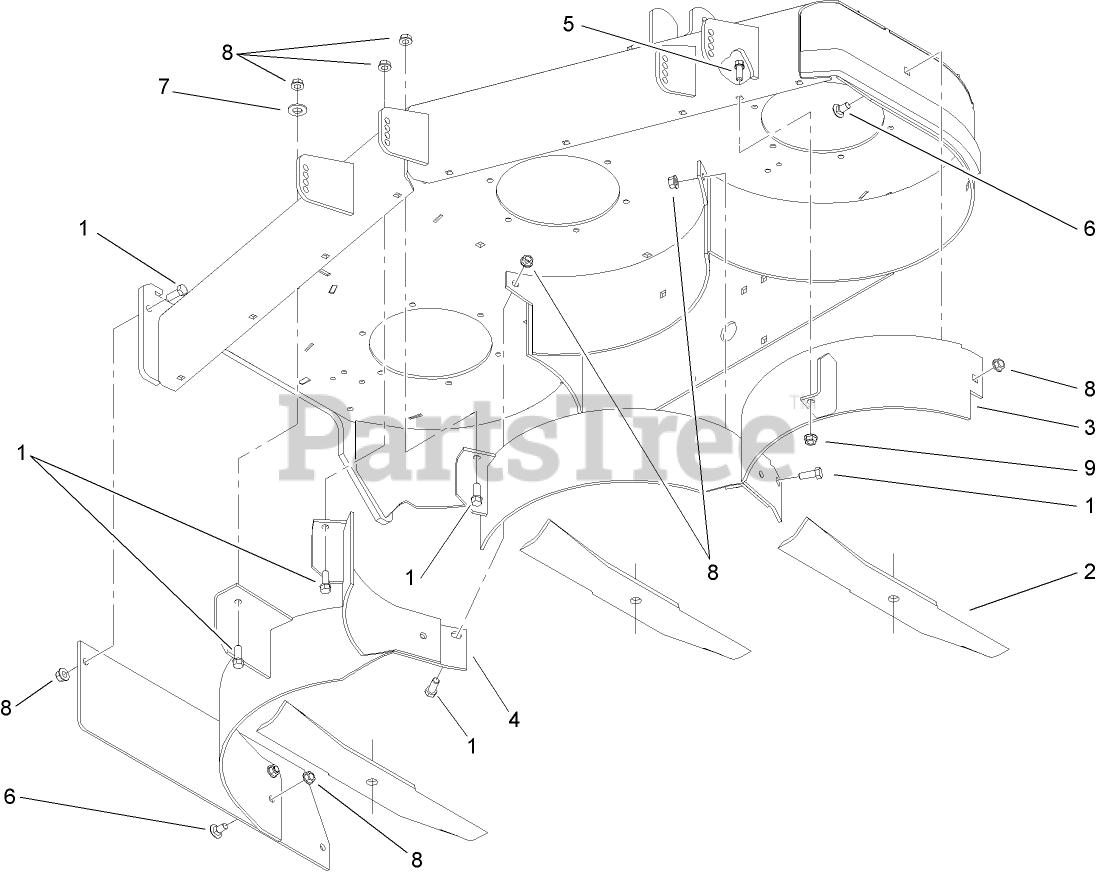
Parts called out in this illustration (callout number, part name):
1	SCREW-HWH
2	BLADE-RECYCLER, 16.5 INCH
3	LEFT BAFFLE ASM
4	RIGHT BAFFLE ASM
5	BOLT-CARR
6	SCREW-CARR
7	WASHER-FLAT
8	NUT-HHF, WHIZ
9	NUT-HF
